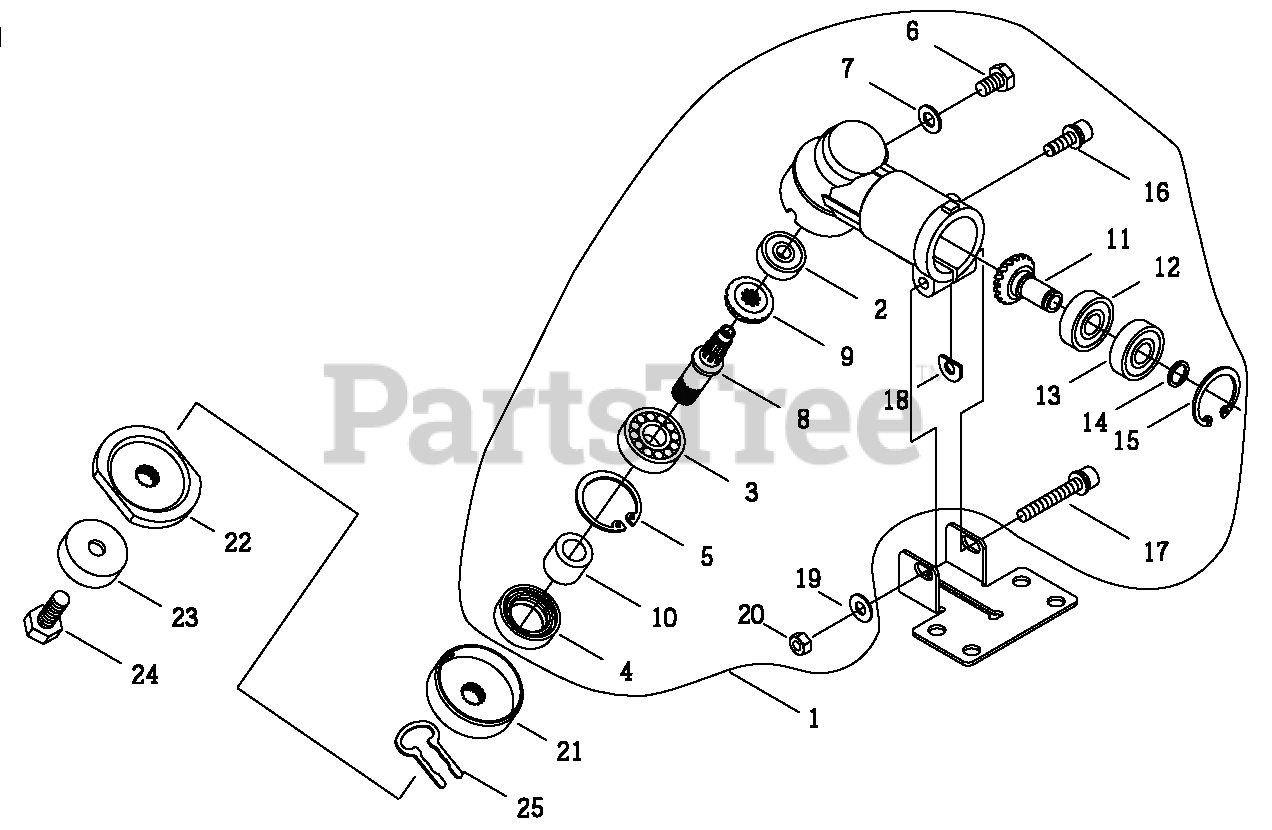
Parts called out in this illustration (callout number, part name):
1	GEAR CASE ASSY
2	BEARING, BALL 626 DDU
3	BEARING, BALL 6000
4	SEAL, OIL
5	RING, SNAP Ø26
6	BOLT M6×10
7	WASHER
8	SHAFT, GEAR
9	GEAR, BEVEL
10	SPACER
11	GEAR, PINION
12	BEARING, BALL 608
13	BEARING, BALL 608ZZ
14	RING, SNAP
15	RING, SNAP Ø22
16	BOLT M5×16
17	BOLT M5×35
18	D-WASHER
19	WASHER 5.5×12×0.8
20	NUT M5
21	PLATE, ADAPTOR - UPPER
22	PLATE, ADAPTOR - LOWER
23	GUARD, BOLT
24	BOLT M7×18
25	CLIP, BLADE
